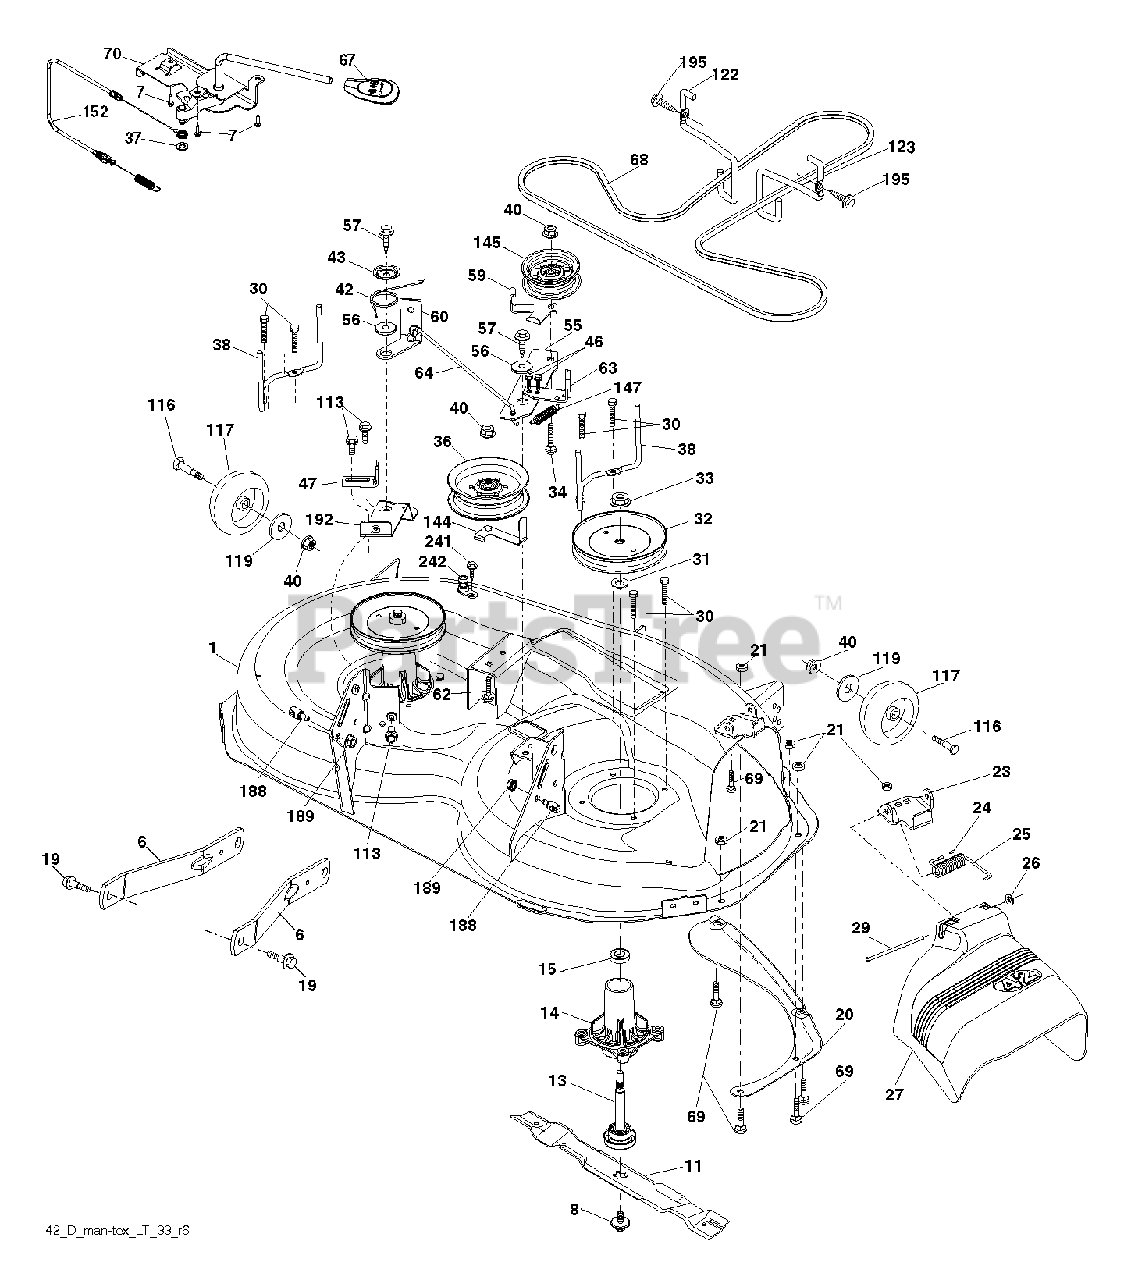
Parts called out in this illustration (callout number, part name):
1	DECK SVC 42" 2GWB 419175X668
6	ARM.SUSPENSION.MOWER.R
7	SCREW.#10 X 0.750.BOS
8	BOLT.WASHER.ASM.7/16-2
11	42" HI-LIFT BLADE
13	SHAFT.ASM.MDRL.N/GREASE.38
14	HOUSING.MANDREL.4PT.
19	BOLT.SHOULDER
20	BAFFLE.VORTEX
21	LOCKNUT
23	BRKT.DEFLECTOR.38"2005+
24	CAP-SLEEVE LT
25	SPRING.TORSION.DEFLECT
26	NUT PUSH M
27	SHIELD.DEFLECTOR.MOWER.42"BLAC
29	ROD.HINGE
30	SCREW, WASHER HEAD
31	WASHER.SPACER.MANDREL
32	PULLEY.MANDREL.5.438.PD
33	NUT.FLANGE.LOCK.TOP
34	BOLT.3/8-16X1.50
36	PULLEY.IDLER.2006
37	WASHER
38	KEEPER.BELT.MANDREL.PULLEY
40	NUT LOCK FLG 3/8-16 UNC
42	SPRING.TORSION.BRAKE
43	SRPING.TORSION.RETAINE
46	SCREW.1/4-20X5/8
47	BRKT.CLUTCH.CABLE
55	IDLER.ARM.42"
56	SPACER.RETAINER
57	SCREW 3/8-16X1
59	GUARD, BELT
60	ARM BRAKE MOWER
63	ARM BRAKE MOWER
64	LINKAGE.BRAKE.ASM.ZINC
67	HANDLE.CLUTCH.CABLE.LT
68	BELT.DECK.DRIVE.42"
69	BOLT
70	CLUTCH.ASM.MANUAL.YT.PREDATORQ
113	BOLT.5/16HEX.WHS.HD
116	BOLT M
117	WHEEL.GAGE.HALF.SPOKED
119	WASHER
122	KEEPER BELT ENGINE LH
123	KEEPER BELT RH
144	KEEPER.BELT.MOWER
145	PULLEY.IDLER.48"PRIMARY
147	RETURN SPRING
152	CABLE.CLUTCH.MANUAL.
188	STUD.FASTNER.W/ANTI-ROTATE
189	NUT LOCK HEX FLANGE 5/16-18
192	BRKT.BRAKE.STAND.LH.
195	SCREW, 3/8-16X3/4
241	SCREW.TT.#10-32X.5.3/8.FLANGE
242	PORT.WASHOUT
